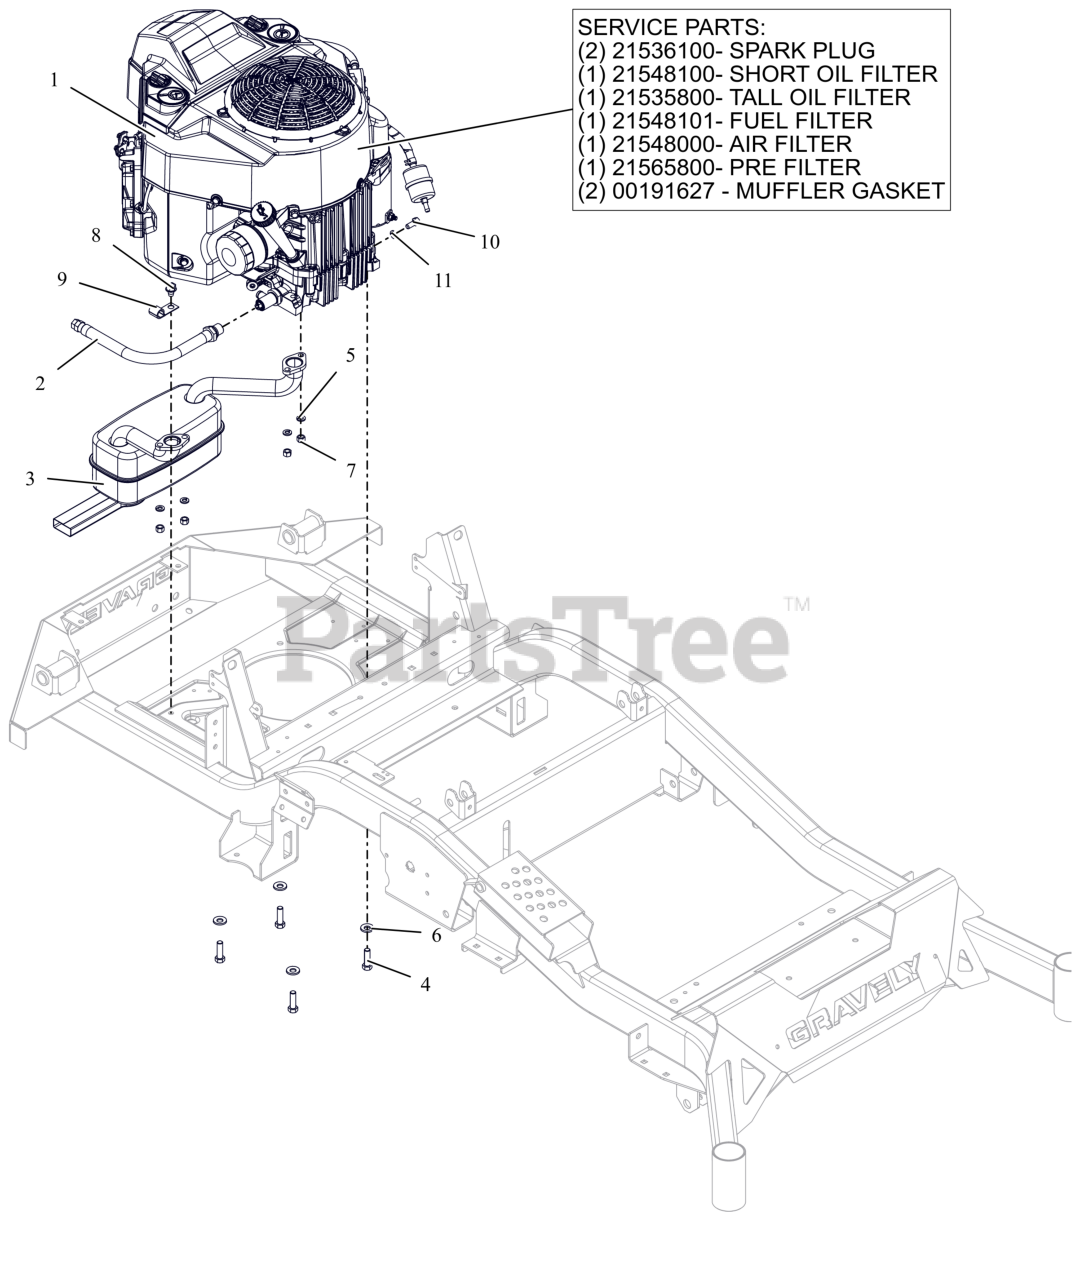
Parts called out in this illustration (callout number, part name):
1	ENGINE, KAWASAKI FS691V
1	PLUG, SPARK
1	OIL FILTER, KAWASAKI FR
1	FILTER,OIL - KAW
1	FUEL FILTER-KAWASAKI FR
1	AIR FILTER, KAWASAKI FR
1	PRE FILTER, KAWASAKI FS
1	GASKET, MUFFLER S/O
2	HOSE, OIL DRAIN
3	MUFFLER, KAWASAKI
4	BLT, HEX .38-16X1.25 G5 ZCC NT
5	WSHR,LK-REG .312X.078 ZCC
6	WASHER, 3/8" SPRING DISC
7	NUT-LK-TOP-FLG M8 ZCC
8	SCR,TAP .375-16X.50 HWH TR ZCC
10	BLT, HEX M8-1.25X20 G8.8 ZCC
11	WSHR,LK-REG .312X.078 ZCC
